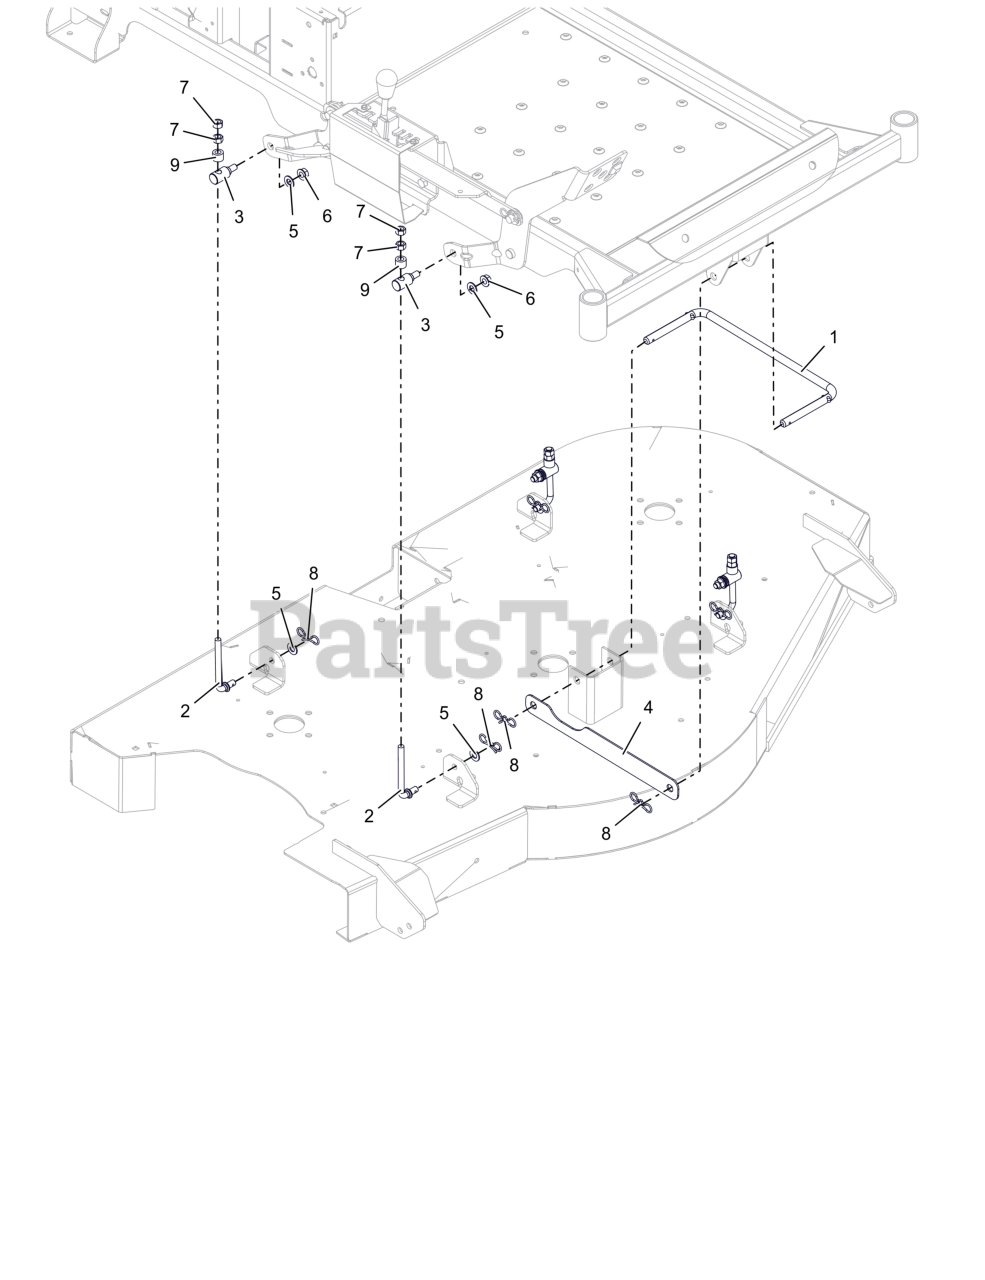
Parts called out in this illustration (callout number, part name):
1	WIREFORM- DRAG LINK
2	WIREFORM- DECK ADJUSTMENT
3	TRUNNION- DECK ADJUSTER
4	STRAP- DRAG LINK
5	WSHR,FLT .406X.812X.065 ZCC
6	NUT-LK-CTR-FLG .375-16 GF ZCC
7	NUT-STD .375-16 G2 ZCC
8	PIN, BOWTIE .091X1.875 ZCC
9	BSHG-SLV .391X.688X.52 PM
